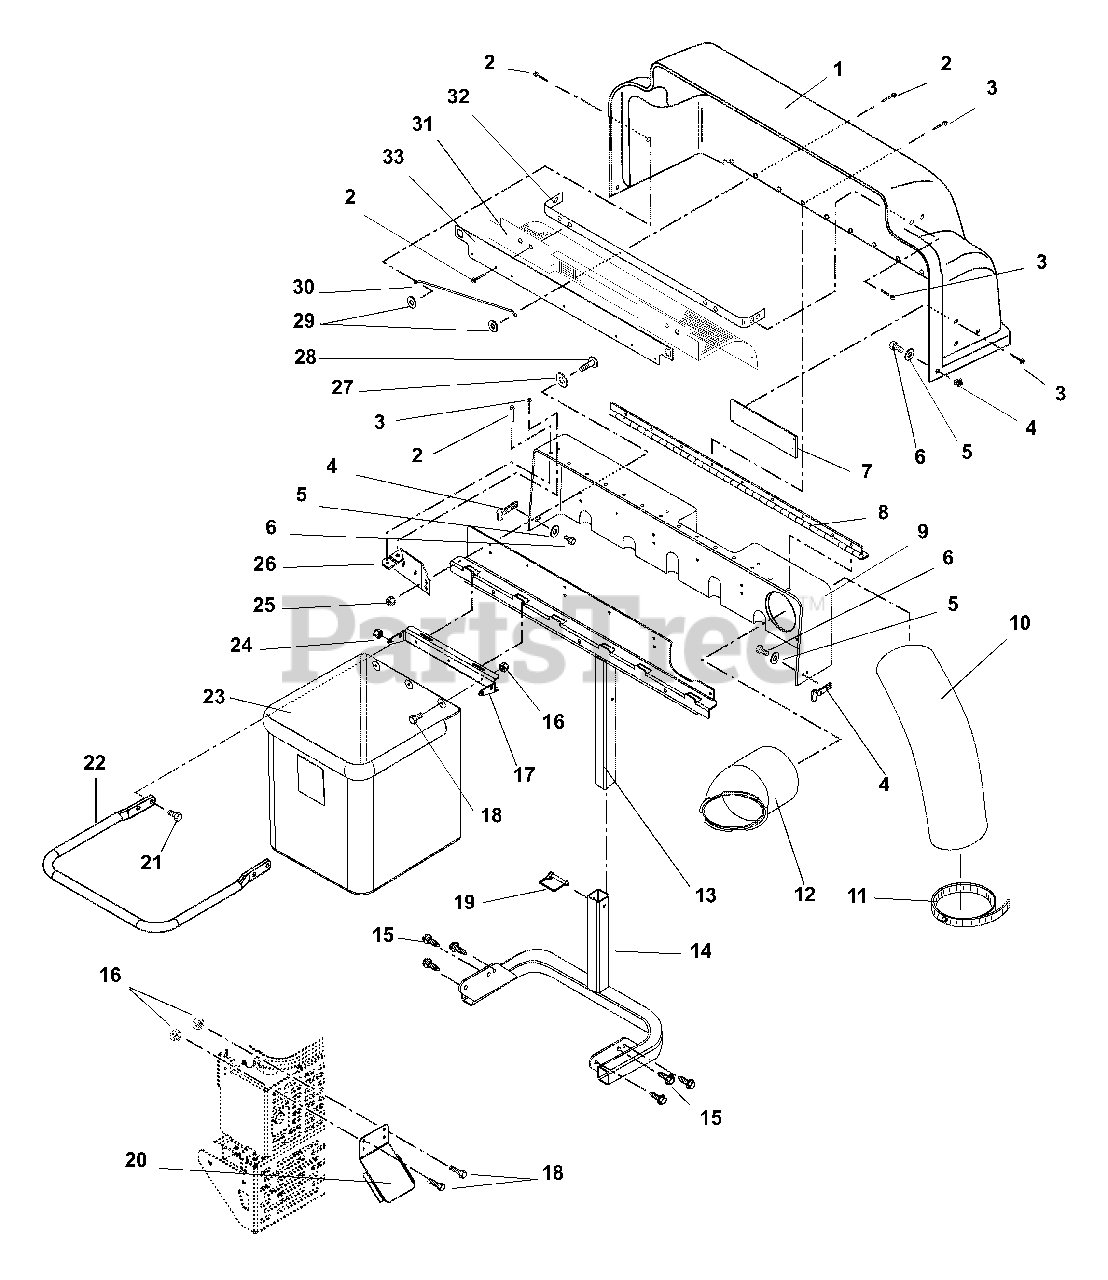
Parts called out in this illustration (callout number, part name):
1	Hinged Cover with Decal
2	Rivet-Pop .187 x .527
2	(Gravely Part Number)
3	Rivet-Pop .187 x .402
4	Latch, Rubber
5	Washer-Flat-Steel .219 x .50 x .049
6	Screw-Machine 10-24 x .50 Hex Washer Head
9	Stationary Cover
9	(Gravely Part Number)
10	Hose 52.5"Long
11	Clamp-Hose Worm 2.13/8.62 x .56
11	(Gravely Part Number)
12	Bagger Boot- Upper
12	(Gravely Part Number)
13	Weldment-Bagger Frame
14	Weldment-Bumper
15	Screw, Tapping, .38-16 x .75
16	Nut-Locking-Center .25-20
17	Clamp-Bag
18	Bolt-Hex .25-20 x .50 Grade 5
19	Pin-.38 x 2.50 Square Lock
20	Deflector, Exhaust
21	Bolt-Round Head Square Short Neck .31-18 x .75 Grade 5
22	Frame-Bag Support
23	Bag-Mesh Assist Bagger
24	Nut-Spin Lock-Flange .312-18
25	Nut- Locking-Nylon .312-18 Grade 2
26	(Gravely Part Number)
27	Washer-Flat-Steel .344 x .063
28	Bolt-Hex .31-18 x 1.00 Grade 2
29	Washer-Flat-Steel .219 x .50 x .049
30	(Gravely Part Number)
32	Screen Mounting Bracket
33	Guard, Screen
